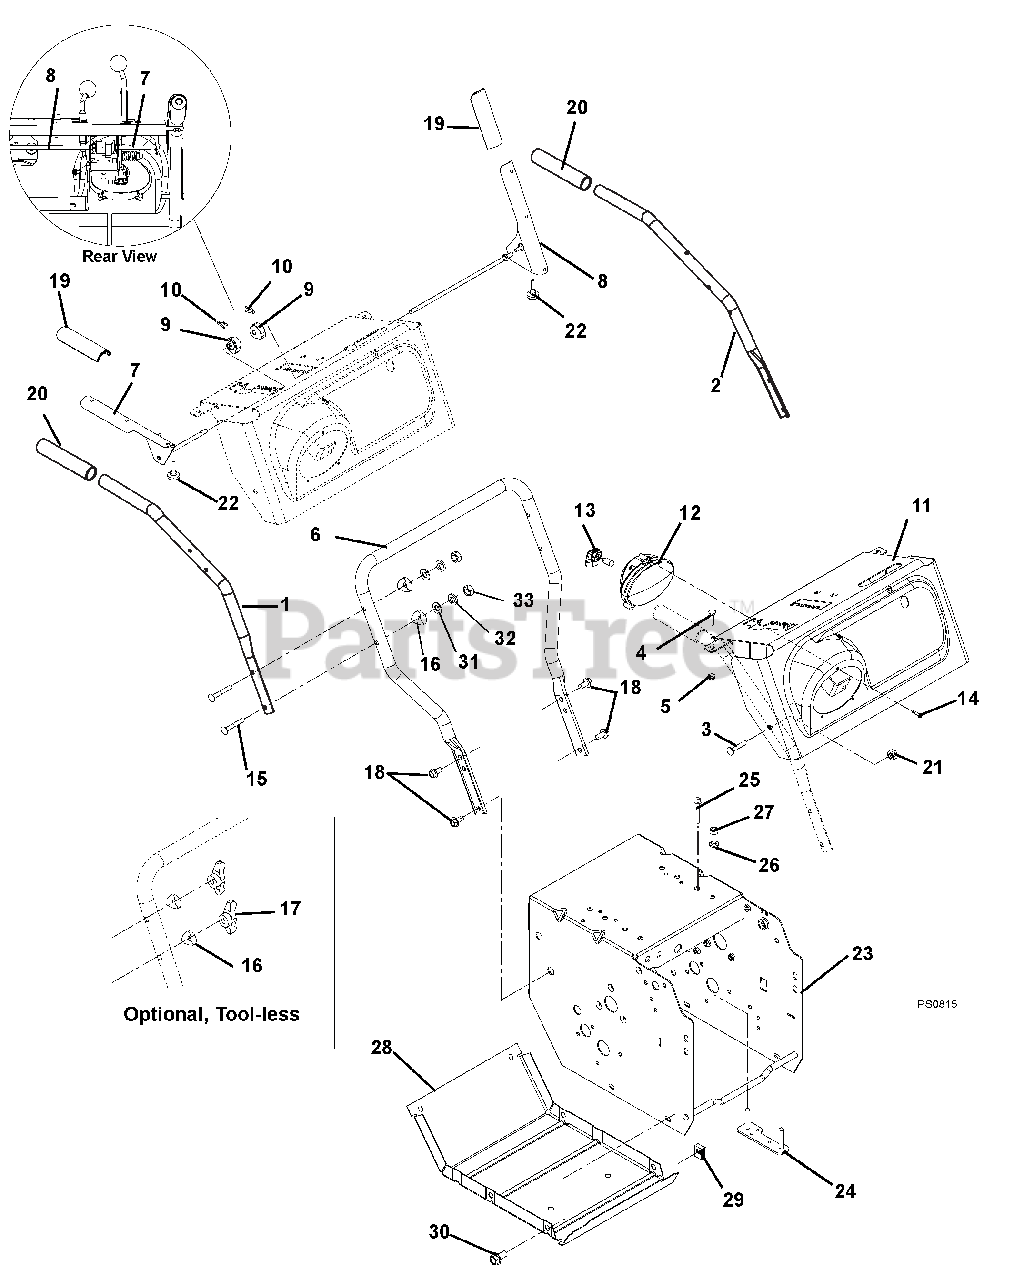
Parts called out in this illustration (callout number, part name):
1	HANDLEBAR, UPPER-RH
2	HANDLEBAR, UPPER-LH
3	@BLT-RDHDSQNK .31-18X1.75 G5YZ
4	BLT-RDHDXLSQNK.25-20X1.25 G5ZC
5	@NUT-LK-TOP-FLG .25-20 YWZC
6	HANDLEBAR, LOWER - DELUXE
7	LEVER, RH-ATTACHMENT
8	LEVER, LH-TRACTION
9	CAM, INTERLOCK
10	PIN, SPRING CLIP
11	DASH PANEL W/CONTROL DECAL
11	CONTROL PANEL W/DECAL
11	PANEL-W/CONTROL DECAL
12	LIGHT, HALOGEN ASSY.
13	BULB, LIGHT-HALOGEN 20W
14	SCR-TAP 10-16X.75 HI-LO PPH
15	@BLT-RDHDSQNK .31-18X2.25 G5YZ
16	SPACER, HANDLEBAR
17	KNOB - WING .312-18 UNC
18	BLT-SERHFWH .38-16X.75 YWZC
19	GRIP, CLUTCH LEVER, LH AND RH
20	HANDLE GRIP
21	@NUT-LK-CTR .31-18 YWZC
22	BUMPER, RUBBER - PULL MOUNT
23	FRAME, MAIN
24	STRAP, ENGINE BOLT-WELDMENT
25	RVT-POP .187 YZ
26	WSHR-LK .312X.097 HVY YWZC
27	@NUT-HEX .31-18 YWZC
28	COVER, BOTTOM
29	NUT-RTNR .25-20X.56
30	BLT-HEX .25-20X.75 HWH YZ GR5
31	@WSHR-FL-STL.38X.875X.083 YWZC
32	@WSHR-LK .31X.078 REG YWZC
33	@NUT-LK-NYL .312-18 YWZC
